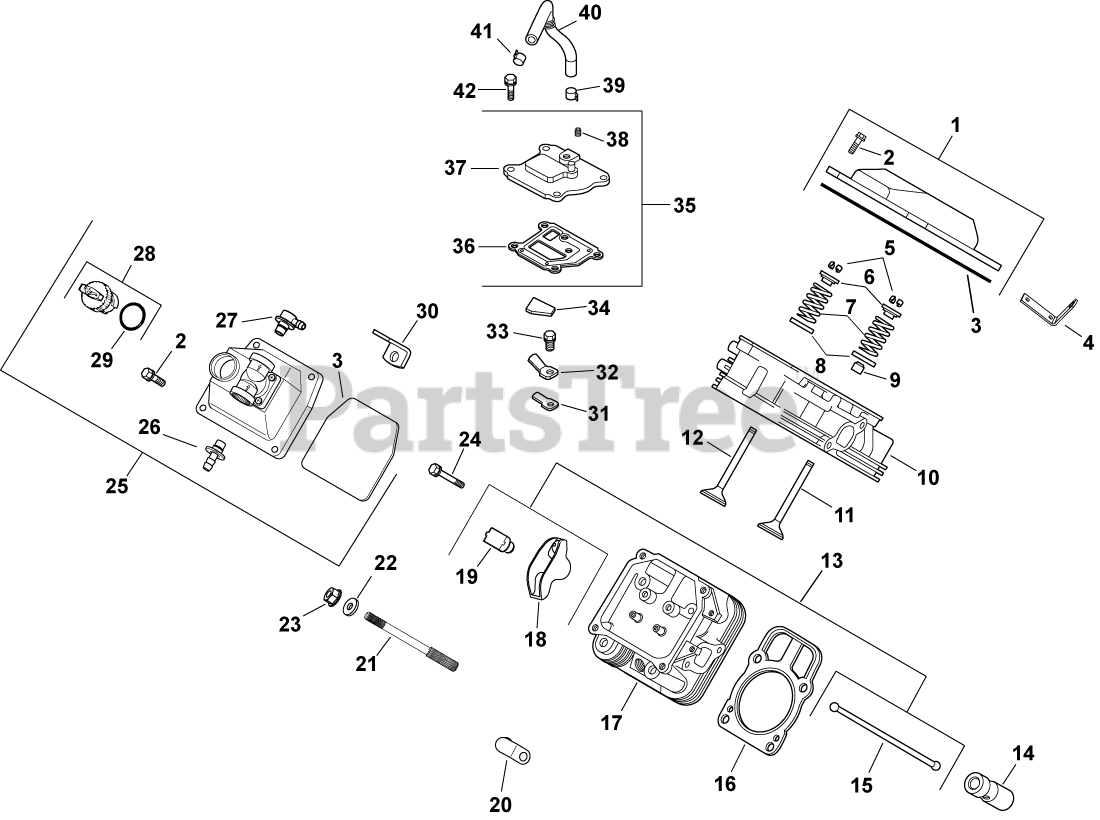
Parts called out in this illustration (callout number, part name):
1	KIT, VALVE COVER-PLAIN
2	SCREW, FLG M6X1.0X30
3	O-RING (YELLOW), VALVE COVER
4	STRAP, LIFTING-USE 25 445 03-S
5	KIT, RETAINER
6	RETAINER, VALVE SPRING - USE 25 173 28-S
7	SPRING, VALVE
8	RETAINER, SPRING
9	SEAL, VALVE STEM - (#2503214S)
10	HEAD, SERVICE ASSY CYL #1-USE 24 318 106
11	VALVE, INTAKE (STD)
12	VALVE, EXHAUST (STD) - USE 32 016 01-S
13	KIT, VALVE TRAIN
14	LIFTER, HYDRAULIC VALVE-USE 25 351 10-S
15	ROD, PUSH
16	CYL HEAD GASKET KIT-USE 24 841 04-S
17	HEAD, SERVICE ASSY CYL #2-USE 24 318 114
18	ARM, ROCKER
19	PIVOT, ROCKER ARM
20	KIT, HI TEMP CUTOUT SENSOR
21	STUD, M8X1.25
22	WASHER, FLAT 8.6 MM
23	NUT, FLG M8X1.25
24	SCREW, FLG M6X1.0X34
25	KIT, VALVE COVER-FUEL PUMP
26	KIT, STRAIGHT FITTING
27	KIT, 90 DEG. FITTING
28	CAP ASSY, OIL FILL (YELLOW)
29	O-RING-USE 24 153 32-S
31	REED, BREATHER
32	RETAINER, REED
33	SCREW, FLG THD FRM M5X.8X10
34	FILTER, BREATHER-USE 24 050 11-S
35	KIT, BREATHER ASSEMBLY
36	GASKET, BREATHER-USE 24 041 67-S
37	COVER, BREATHER -USE 24 033 01-S
38	PLUG, CTSK PIPE 1/8"
39	CLAMP, HOSE (KM)-USE 25 237 31-S
40	HOSE, BREATHER
41	CLAMP, BAND SPRING HOSE-(#2523737S)
42	SCREW,FLG THD FRM M6X1.0X20-(#25086396S)
2401602-S	VALVE, EXHAUST (.25)
2401702-S	VALVE, INTAKE (.25)
24755147-S	KIT, CYLINDER HEAD HARDWARE
